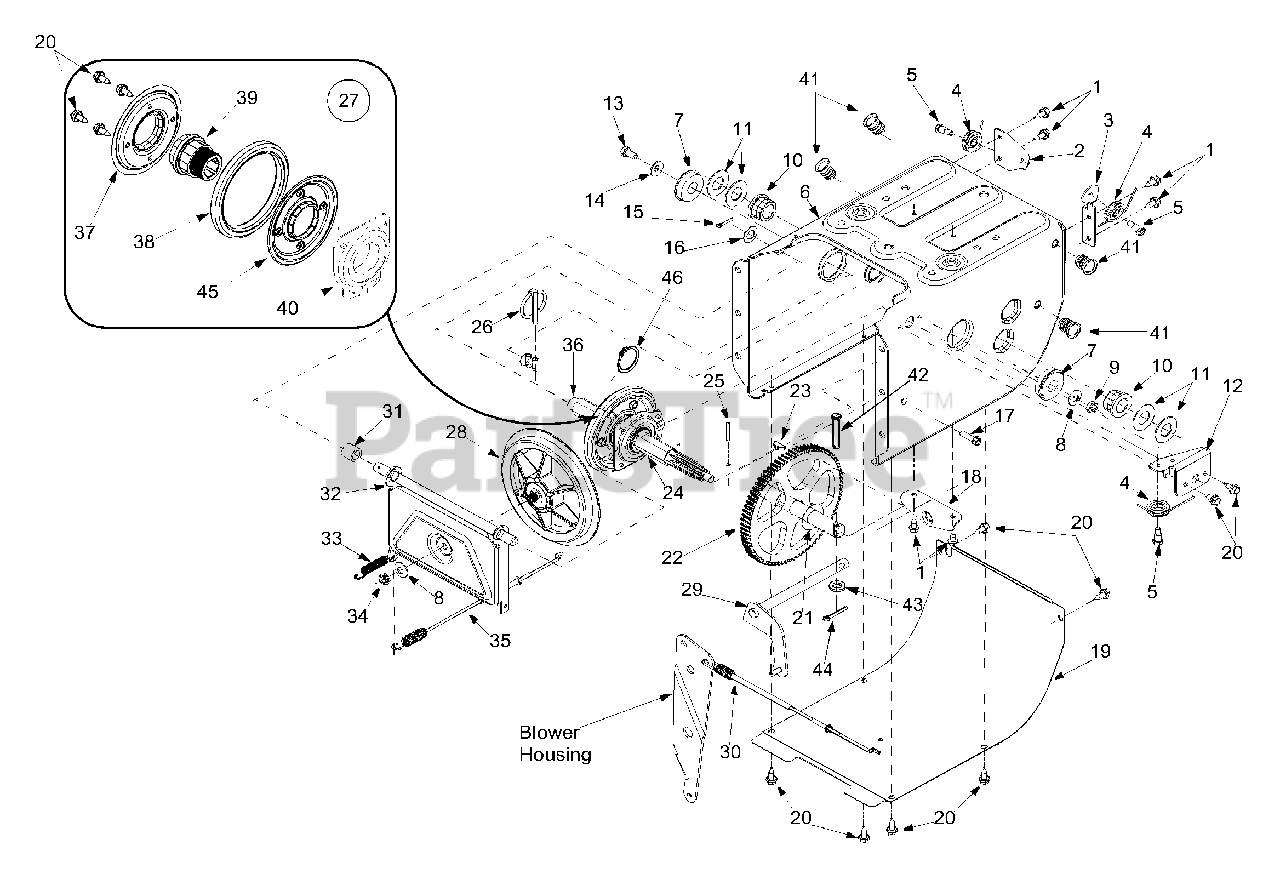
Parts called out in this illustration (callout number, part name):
1	Self-Tapp. Screw 1/4-20 x 0.5"
5	Hex Screw 1/4-28
6	Frame Assembly
7	Ball Bearing
8	Bell Washer
9	Lock Jam Nut
10	Hex Flange Bearing
11	Flat Washer
14	Bell Washer.340 ID x.872 OD
15	Cotter Pin
16	Flat Washer.536 ID x.930 OD
17	Self Tapp. Screw 1/4-20 x 1.25"
21	Flat Washer.760 ID x.50 OD
24	7-Tooth Shaft
25	Roll Pin
26	Click Pin
27	Friction Wheel Assembly
28	Friction Disc Wheel
29	Wheel Shift Rod Assembly
30	Drive Cable, Auger
31	Spacer
34	Jam Nut 3/8-24
35	Drive Cable, Clutch
36	22.2" Axle (used w/ 13 x 4 tire)
36	21.4" Axle (used w/ 13 x 5 tire)
37	Friction Plate
38	Friction Wheel Rubber
39	Friction Wheel Hub
40	Friction Wheel Bearing Assembly
41	Nut Insert
42	Clevis Pin
43	Flat Washer.281 ID x.50 OD
44	Cotter Pin
45	Friction Plate
46	Snap Ring
